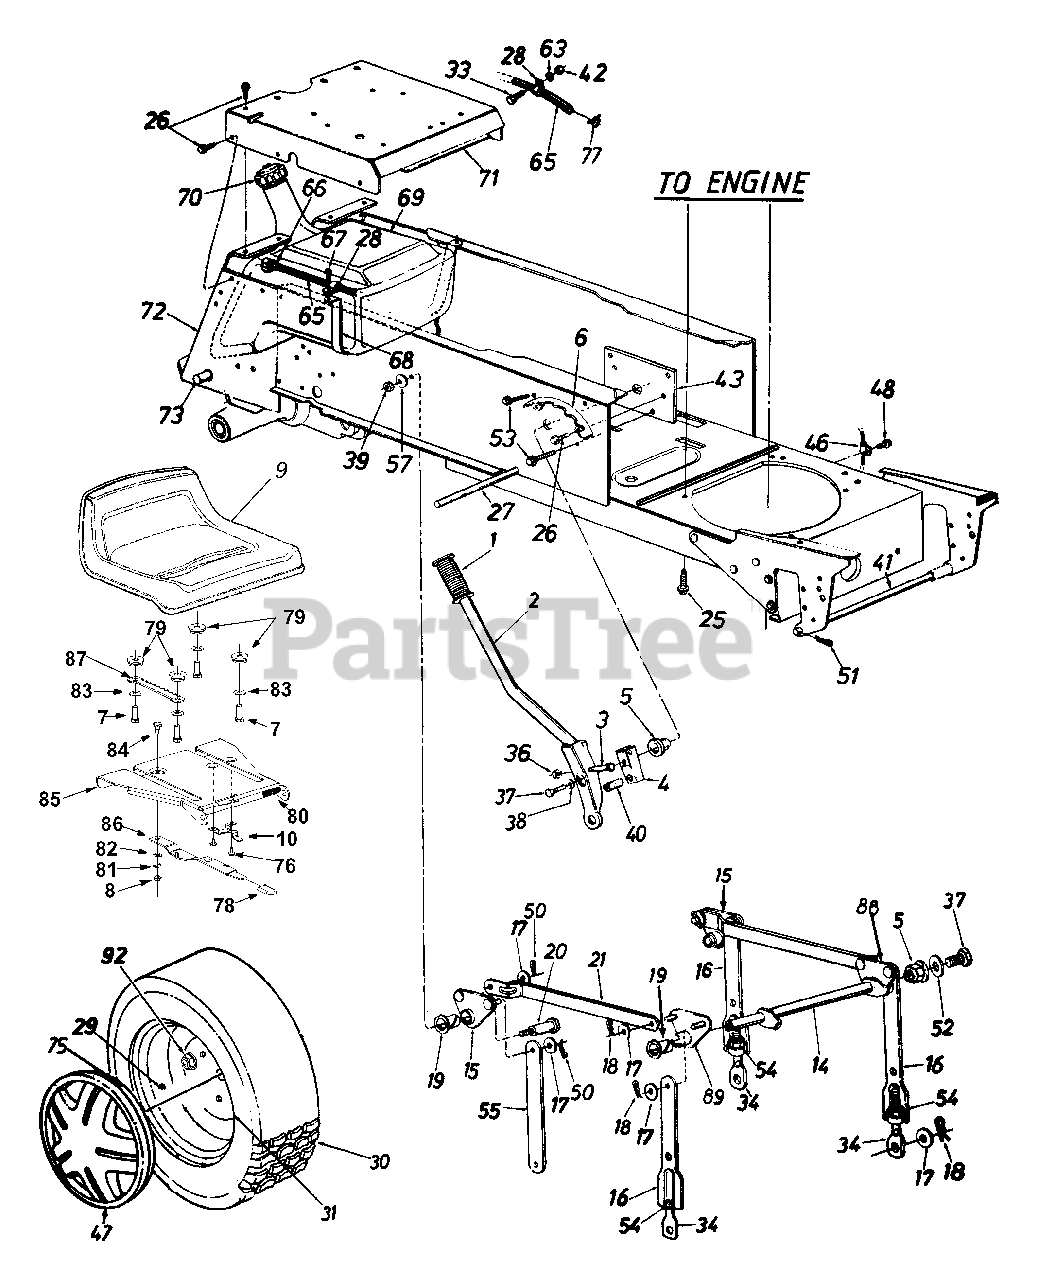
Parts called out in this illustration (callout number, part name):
1	Grip
2	Lift Handle Ass'y.
3	Hex Bolt 5/16-18 x 1.5" Lg.
4	Lift Shaft Drive
5	Plastic Hex Brg. 5/8" I.D.
8	Hex Flanged L-Nut 1/4-20 Thd.
9	Seat
14	Lift Shaft Ass'y.
15	Lift Pivot Brkt. Ass'y.
17	Fl-Wash. 1/2" I.D. x 1.00" O.D. x .090"
18	Hairpin Cotter
19	Flanged Brg. 5/8" I.D.
20	Shld. Bolt 5/8" Dia. x .96" Lg. 3/8-16
26	Hex Thd. Rolling Scr. 5/16-18 x .75"
27	Running Board Rod
29	Air Valve
33	Hex Bolt 1/4-20 x .62" Lg.
34	Eye Bolt Adj. Link 1/2-13 Thd.
36	Hex Cent. L-Nut 5/16-18 Thd.
37	Hex Bolt 5/16-24 x .75" Lg. (Gr. 5)
39	Hex Top L-Nut 3/8-16 Thd.
40	Compression Spring
41	Deck Connecting Rod
42	Hex Sems Nut 1/4-20 Thd.
48	Hex Wash. Hd. TT-Tap Scr.
50	Cotter Pin .09 Dia. x 1.0" Lg.
51	Int. Cotter Pin
52	Flat Wash. .34" I.D. x 1.12" O.D.
53	Hex Wash. Hd. AB-Tap Scr.
54	Hex Nut 1/2-13 Thd.
57	Bell-Wash. .4" I.D. x 1.13" O.D.
63	L-Wash. 1/4" I.D.
65	Fuel Line 46" Lg.
67	Hex AB-Tap Scr. 1/4 x .62" Lg.
68	Fuel Tank Strap
71	Seat Plate
75	Spring Clip
76	Hex Wash. Hd. Tap Scr.
78	Seat Adjustable Grip
80	Compression Spring
81	Spring Wash. .265" I.D.
82	Flat Washer .344" ID
83	Flat Washer .531 x .93
84	Shld. Bolt .34" x 1/4-20 Thd.
87	Seat Selector
88	Lift Pivot Brkt. - L.H.
89	Lift Pivot Brkt. - R.H.
92	Lug Nut 7/16-14 Thd.
